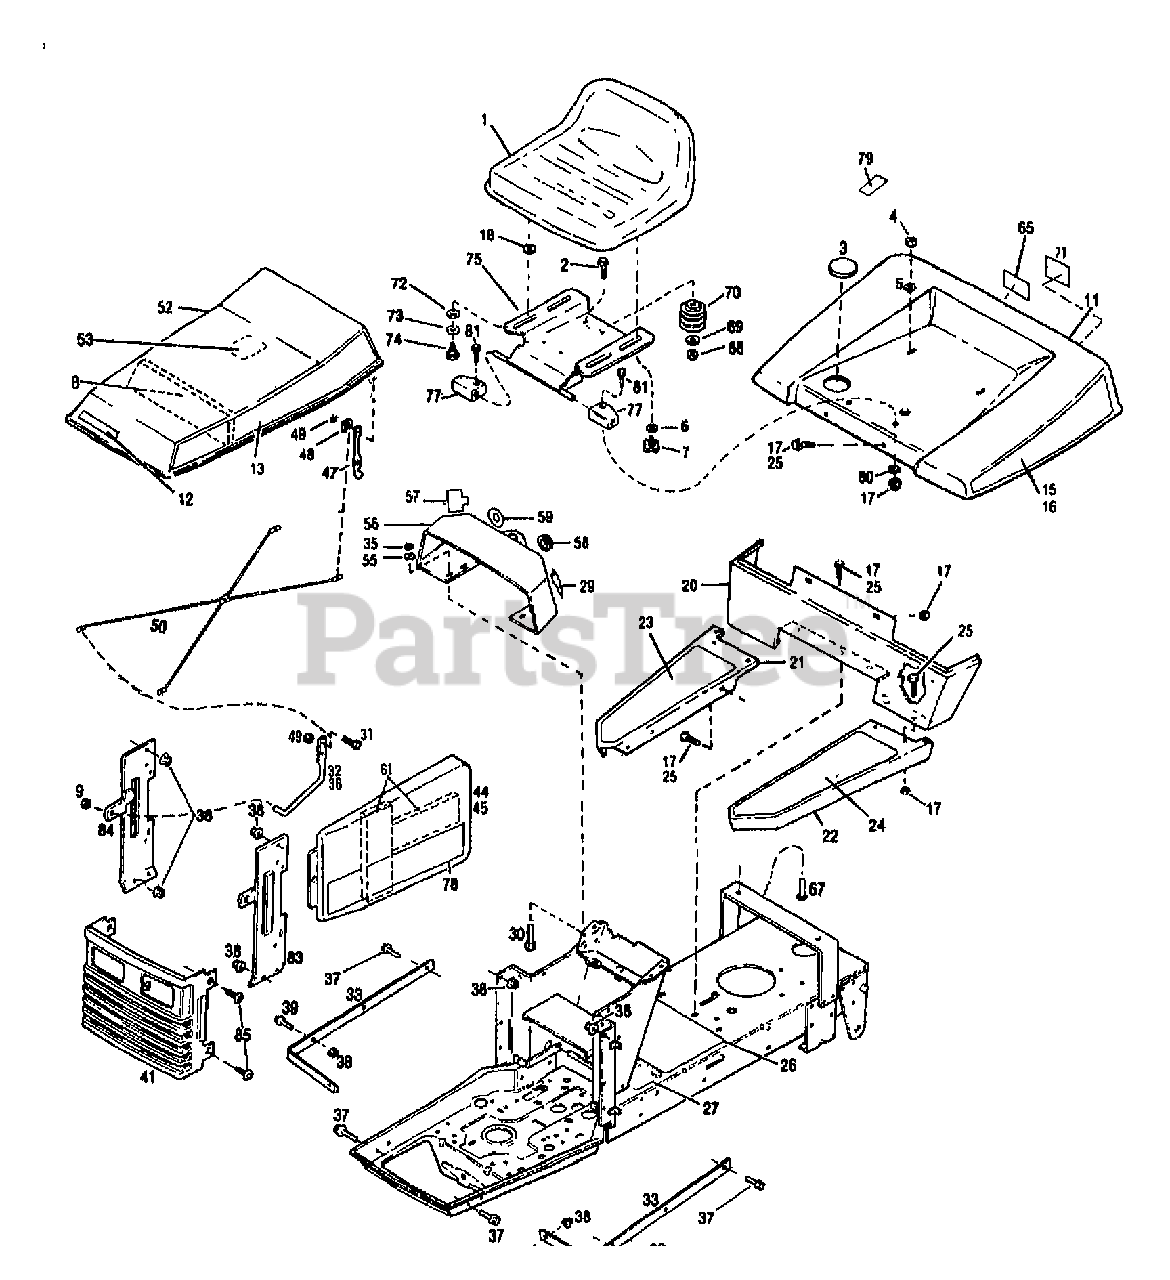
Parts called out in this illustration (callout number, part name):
1	SEAT {13064}
1	SEAT {13065,13066}
2	SCR-HFLK 3/8-16X1.00 ZP
4	NUT-TOP/LK 5/16-18 ZP
5	WASHER-1.25X.343X.059 {13065,13066}
6	WASHER-FLAT 3/8 SAE
8	FOAM-UPPER {13065,13066}
9	NUT-SPECIAL
11	FENDER-REAR
12	DECAL-LOGO
13	DECAL-LOGO
15	DECAL-FENDER {13066}
15	DECAL-FENDER RH RED {13065}
15	DECAL-FENDER RH {13064}
16	DECAL-FENDER LH {13066}
16	DECAL-FENDER LH RED {13065}
16	DECAL-FENDER LH {13064}
17	NUT-HFLK 5/16-18 ZP
18	WASHER-FLAT
20	SUPT-RUNNING BOARD
21	BOARD-RUNNING RH
22	BOARD-RUNNING LH
23	PAD-FOOT RH
24	PAD-FOOT LH
25	SCR-LOCK
26	PAD-FOOT
27	DECAL-OPERATING INST
29	DECAL-CHOKE {13064}
29	DECAL-CHOKE {13065,13066}
30	SCR-HH 1/4-20X.625 G5 ZP
31	SCR-HHS 10-24X.625 ZP
32	LINK-HINGE RH
33	ASSM-HINGE STRAP
35	NUT-HT/LK 1/4-20
36	LINK-HINGE LH
37	SCR-HH 1/4-20X.625
38	NUT-HF/LK 1/4-20 ZP
39	SCR-HFLK 1/4-20X.50 ZP
44	COVER-SIDE LH
45	COVER-SIDE RH
47	LATCH-RUBBER
49	NUT W/LKWASHER 10-24 ZP
50	SUPPORT-HOOD ROD
52	ASSM-HOOD
53	DECAL-SVC INST
55	WASHER-FLAT 1/4 SAE
56	PANEL-INSTRUCTION
57	DECAL-THROTTLE
58	CAP {13064}
59	DECAL-IGNITION
61	BLOCK-SEALING {13065,13066}
65	DECAL-FUEL
67	SCR-CARR 5/16-18X.75
68	NUT-HFLK 3/8-16 ZP
69	WASHER-FLAT 1.25X.406X.179
70	SPRING-COMPRESSION
71	DECAL-LOGO FENDER
72	WASHER-BOW .74X.52X.01
73	WASHER-1.06X.51X.09 NYLON
74	SCR-SHLDR 3/8-16X.25 G5ZP
75	ASSM-SEAT SUPPORT
77	BLOCK-PIVOT
78	DECAL-SIDECVR LH RED
78	DECAL-SIDECVR RH RED
79	DECAL-U.S.A.
80	WASHER-1.5X.343X.104
81	SCR-HH 5/16-18X1.5 G5 ZP
83	ASSM-SUPPORT LH
84	ASSM-SUPPORT RH
